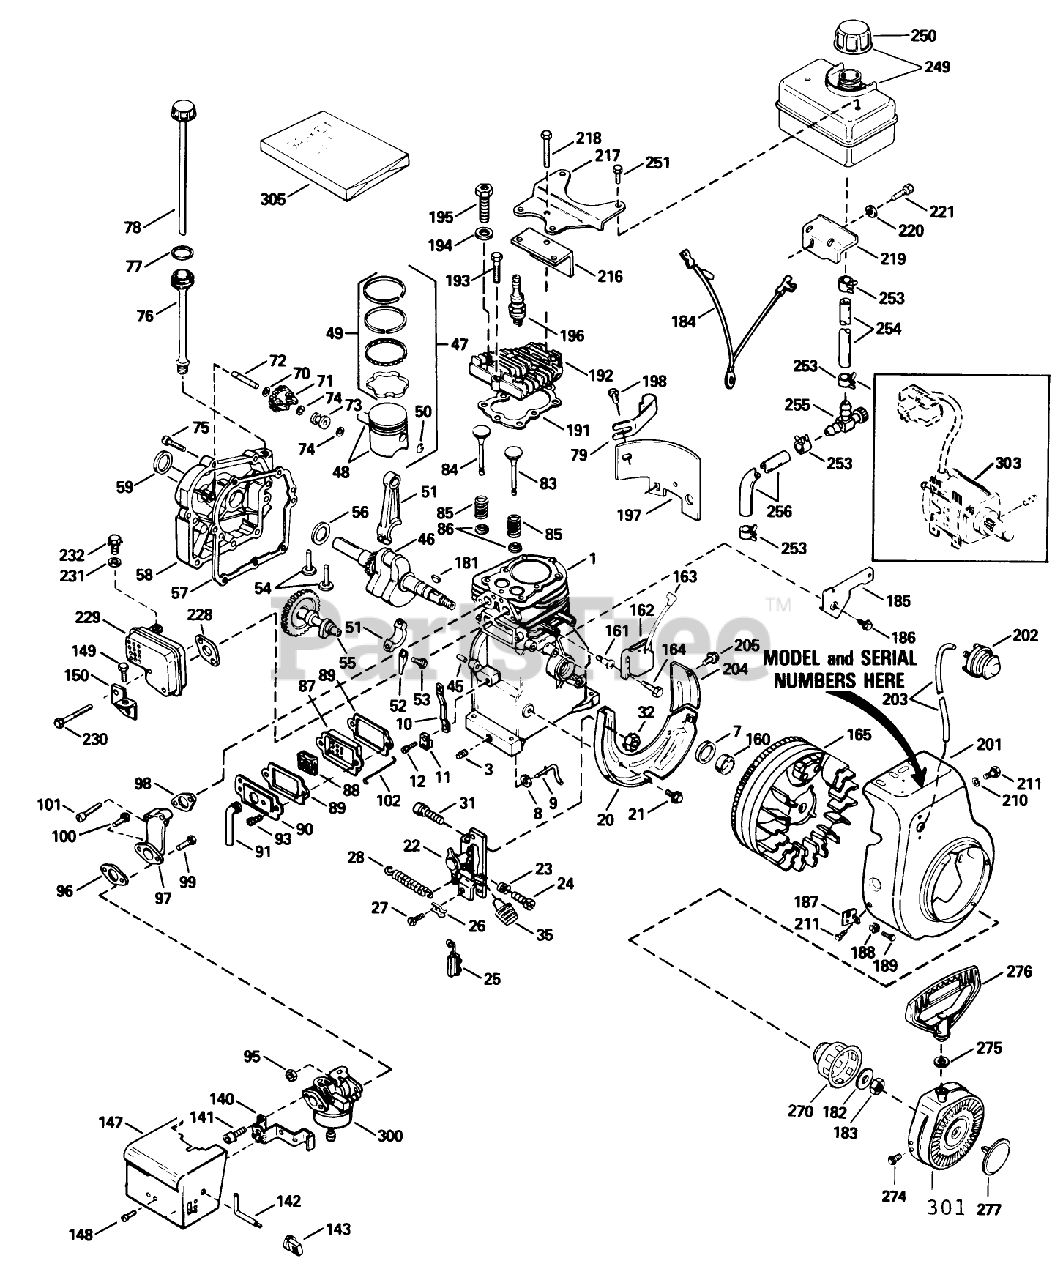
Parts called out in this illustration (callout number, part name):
1	Cylinder Assembly (Incl. Ref. #3, 7 45)
3	Plug-Drain, Oil (SQH 1/4-18)
7	Seal-Oil
8	Washer-Flat
9	Rod-Governor
10	Lever-Governor
11	Clamp-Lever, Governor
12	Screw
20	Baffle-Blower Housing
21	Screw (1/4-20x19/32)
22	Control Assembly, Speed (Incl. Ref. #155 thru 158 160)
23	Spring-Compression
24	Screw
25	Terminal
26	Conduit
27	Screw (10-32 x 3/8)
28	Spring-Extension
31	Screw
32	Nut-Lock
35	Knob-Control
45	Pin-Dowel
46	Crankshaft ASM
47	Piston, Pin Ring Assy., (Incl. Ref. #15 16) (Std.)
47	Piston, Pin Ring Assy., (Incl. Ref. #15 16) (.010 Oversize)
47	Piston, Pin Ring Assy., (Incl. Ref. #15 16) (.020 Oversize)
48	Piston Pin Assy. (Incl. Ref. #16) (Std.)
48	Piston Pin Assy., (Incl. Ref. #16) (.010 Oversize)
48	Piston Pin Assy. (Incl. Ref. #16) (.020 Oversize)
49	Ring Set-Piston Std.
49	Ring Set-Piston .010 oversize
49	Ring Set-Piston .020 oversize
50	Ring-Retaining, Piston Pin
51	Rod Assembly, Connecting (Incl. Nos. 17 18)
52	Dipper-Oil
53	Bolt-Rod, Connecting
54	Lifter-Valve
55	Camshaft
56	Washer-Thrust
57	Gasket-Cylinder Cover
58	Cover-Cylinder (Incl. Ref. #59 72)
59	Seal-Oil
70	Washer-Flat
71	Governor Gear ASM
72	Shaft-Governor
73	Spool-Governor
74	Ring-Retaining
75	Screw (1/4-20 x 1-1/4)
76	Tube-Fill, Oil
77	O-Ring
78	Dipstick
79	Clip-Tube, Fill
83	Valve, Exhaust (Std.)(Incl. No. 40)
83	Valve, Intake (1/32" oversize)(Incl. No. 40)
84	Valve-Intake Standard (Incl. Ref. #151)
84	Valve-Intake 1/32" oversize (Incl. Ref. #151)
85	Spring-Valve
86	Cap-Valve, Spring
87	Body-Breather
88	Element-Breather
89	Gasket-Breather
90	Cover-Breather
91	Tube-Breather
93	Screw
95	Nut and Lock Washer (1/4-28)
96	Gasket
97	Pipe-Intake
98	Gasket-Intake
100	Screw (1/4-28 x 1-11/16)
101	Screw (1/4-20 x 1-19/32)
102	Link-Governor to Throttle
140	Bracket-Choke
141	Screw (10-32 x 1/2)
142	Rod-Choke
143	Knob-Control
147	Cover-Carburetor
148	Screw (8-32 X 5/16)
149	Screw (10-24 x 3/8)
150	Bracket-Cover, Carburetor
160	Spacer
162	Solid State
163	Cover-Spark Plug
164	Screw
165	CLAMP
181	Key-Flywheel
182	Washer-Belleville
183	Nut-Flywheel
184	Wire-Ground
185	Bracket-Hold Down
186	Screw (10-24 x 9/16)
187	Bracket
188	Grommet
189	Screw (8-32 x 3/8)
191	Oil Fill Tube
192	Head-Cylinder (Incl. Ref. #218)
193	Screw (5/16-18x1-1/2)
194	Washer-Flat
195	Screw ( 5/16-18 x 1-1/2)
196	Spark Plug-Resistor (R J19 L M)
197	Extension-Blower
198	Screw
201	Housing-Blower
202	Primer-Asm
203	Line-Primer
204	Baffle-Extension
205	Screw-Hex Washer Hd.
210	Washer
211	Screw
216	Baffle-Heat
217	Plate-Fuel Tank
218	Screw (5/16-18 X 2)
219	Bracket-Fuel Tank
220	Washer
221	Screw Assembly
228	Gasket-Exhaust
229	Muffler
230	Screw-Fil. Hd.
231	Washer
232	Screw
249	Tank Assembly-Fuel (Incl. Ref. #250 253)
250	Cap-Fuel
251	Screw (1/4-15x7/8)
253	Clamp-Line, Fuel
254	Line-Fuel (8.62)
255	Valve-Shut Off
256	Line-Fuel
270	Cup-Starter
274	Screw, Hex Hd.
275	Washer
276	Handle-Starter, Mitten Grip
277	Plug Starter
300	Carburetor (Incl. Ref. #87)
301	Rewind Starter
303	Electric Starter Kit 33290C (Optional) Sold as Accessory
305	Gasket Set (Incl. Items Marked *)
